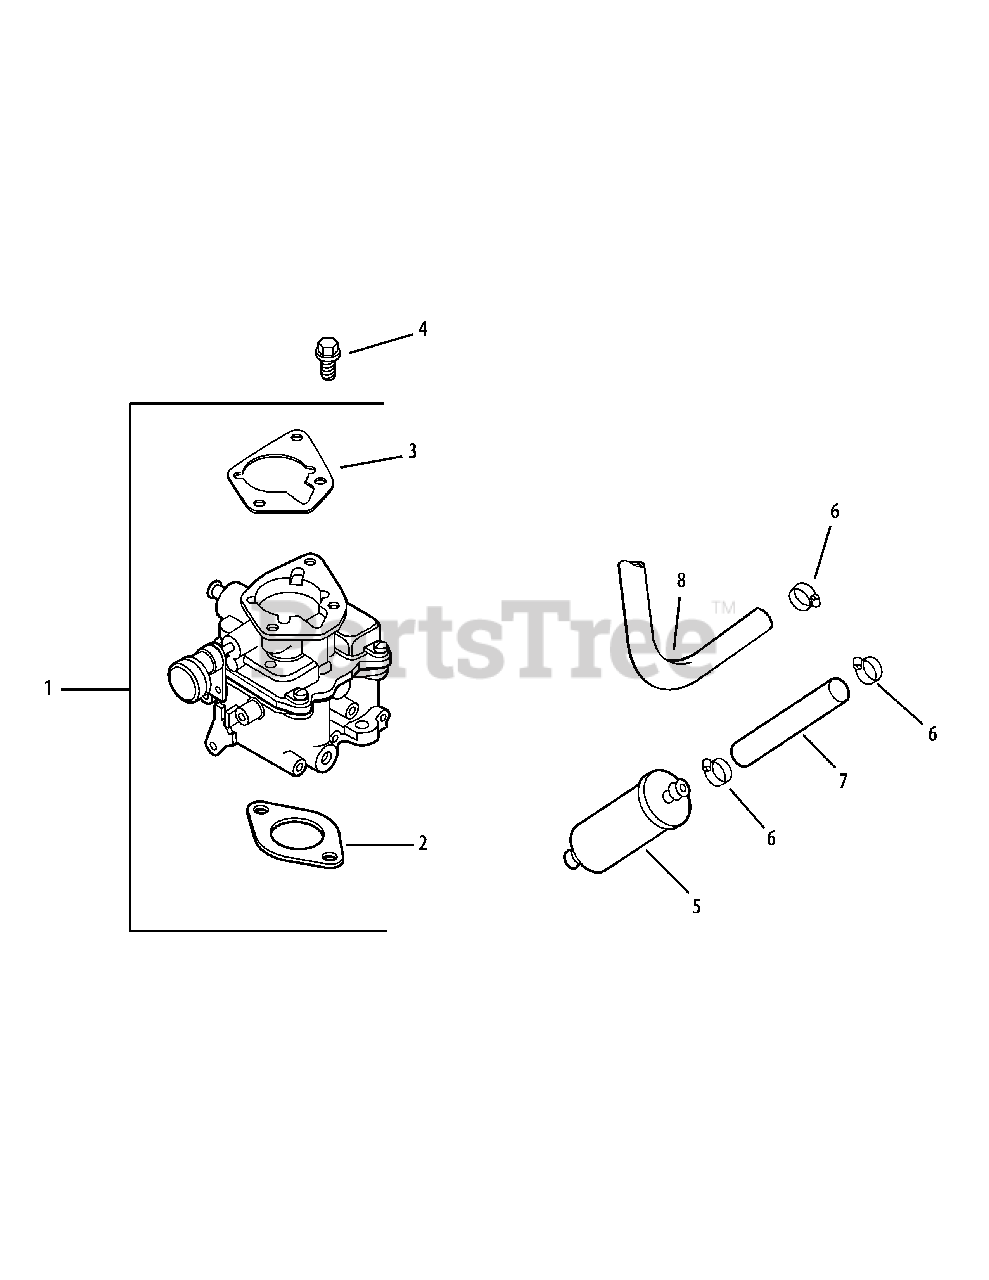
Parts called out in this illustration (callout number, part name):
1	Line, Fuel 10"
2	Clamp, Hose 1/2"
3	Carburetor W/Gaskets KSF
4	Gasket, Air Cleaner Base
5	Gasket, Carburetor
6	Screw, hex Flg M6x1.0x25
7	Filter, Fuel
8	Line, Flex 11" Pump-Pulse (Air Only)
